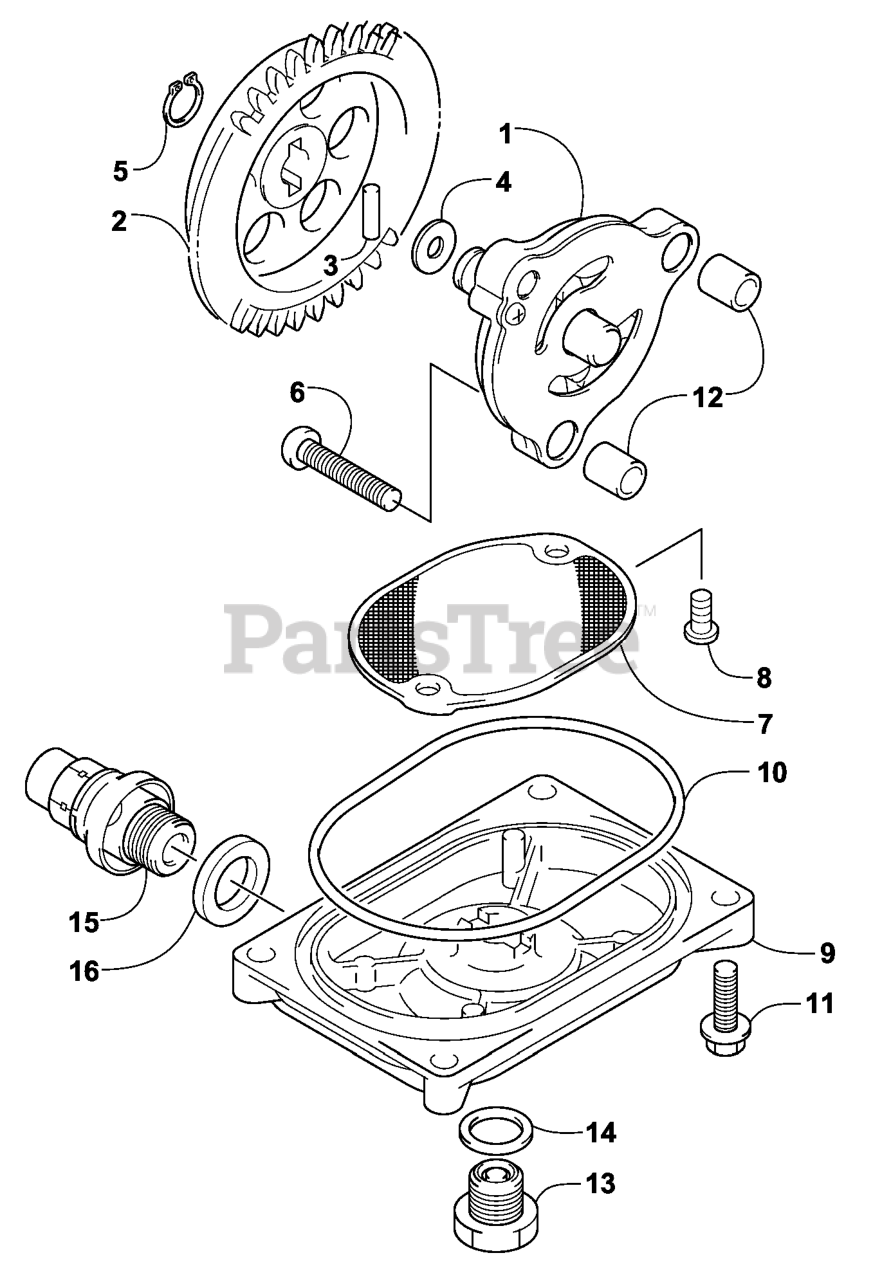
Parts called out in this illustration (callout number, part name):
1	ARM-ASSIST
2	GEAR-DRIVEN
3	PIN-DRIVEN GEAR
5	CLIP-CIR, EXTERNAL
6	BOLT-FLANGE
8	BOLT-WASH
9	CAP-STRAINER, OIL
11	BOLT-FLANGE
12	DOWEL-SLEEVE
13	PLUG-DRAIN, MAGNETIC
14	WASHER-COMPRESSION
